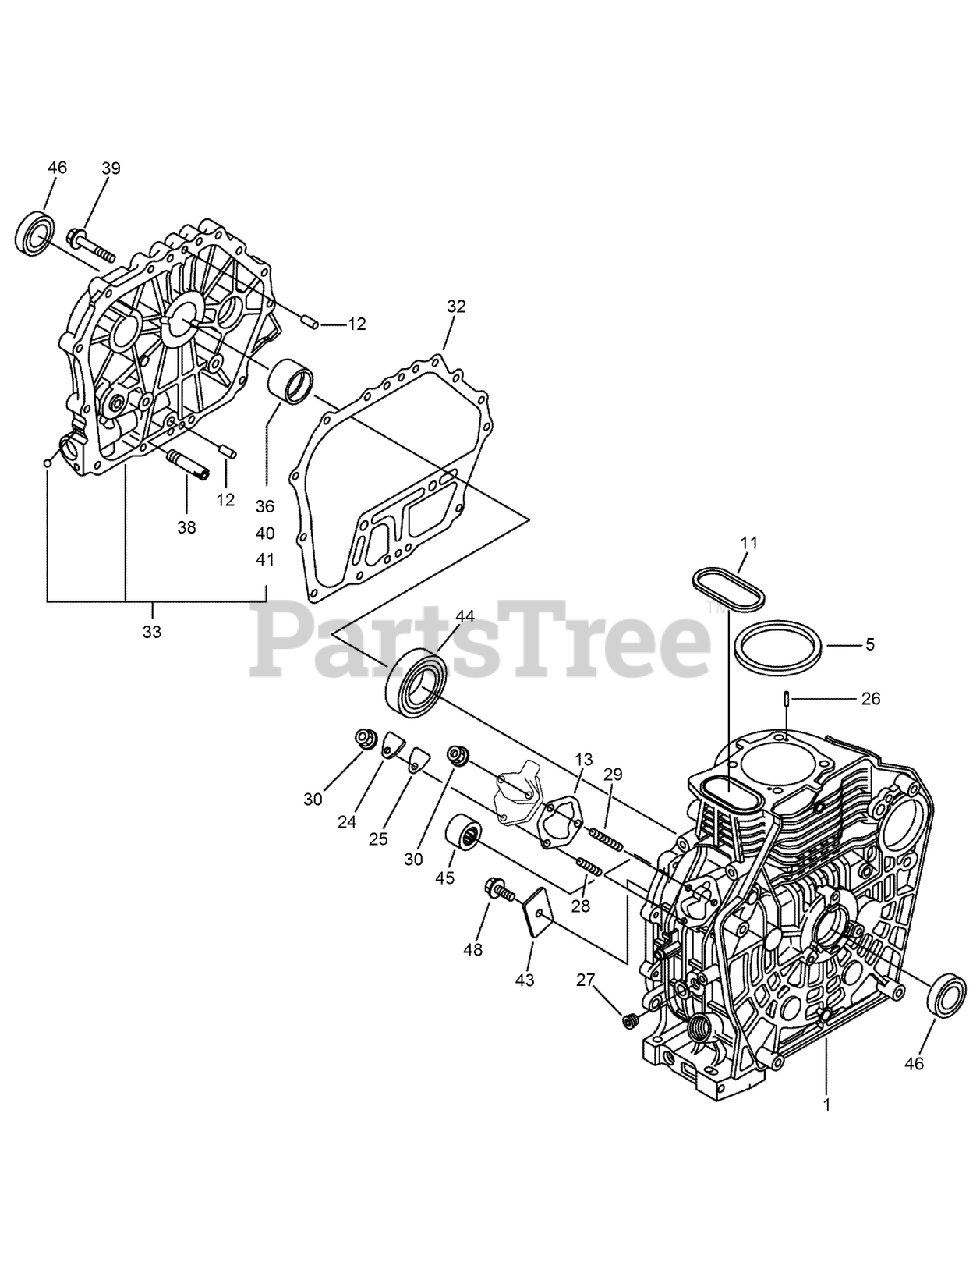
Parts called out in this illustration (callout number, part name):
1	CYLINDER BLOCK ASM
5	GASKET-HEAD, CYLINDER
11	O RING-TAPPET
13	SHIM SET
24	COVER-PUMP
25	GASKET-COVER
28	STUD-BOLT
29	STUD-BOLT
32	GASKET-CASE, CRANK
33	COVER-CASE, CRANK
36	BEARING-MAIN
38	PIPE-INLET, OIL
40	METAL-MAIN, 0.25
41	METAL-MAIN, 0.5
43	RETAINER-BEARING
44	BEARING
45	BEARING-NEEDLE
46	SEAL-OIL
